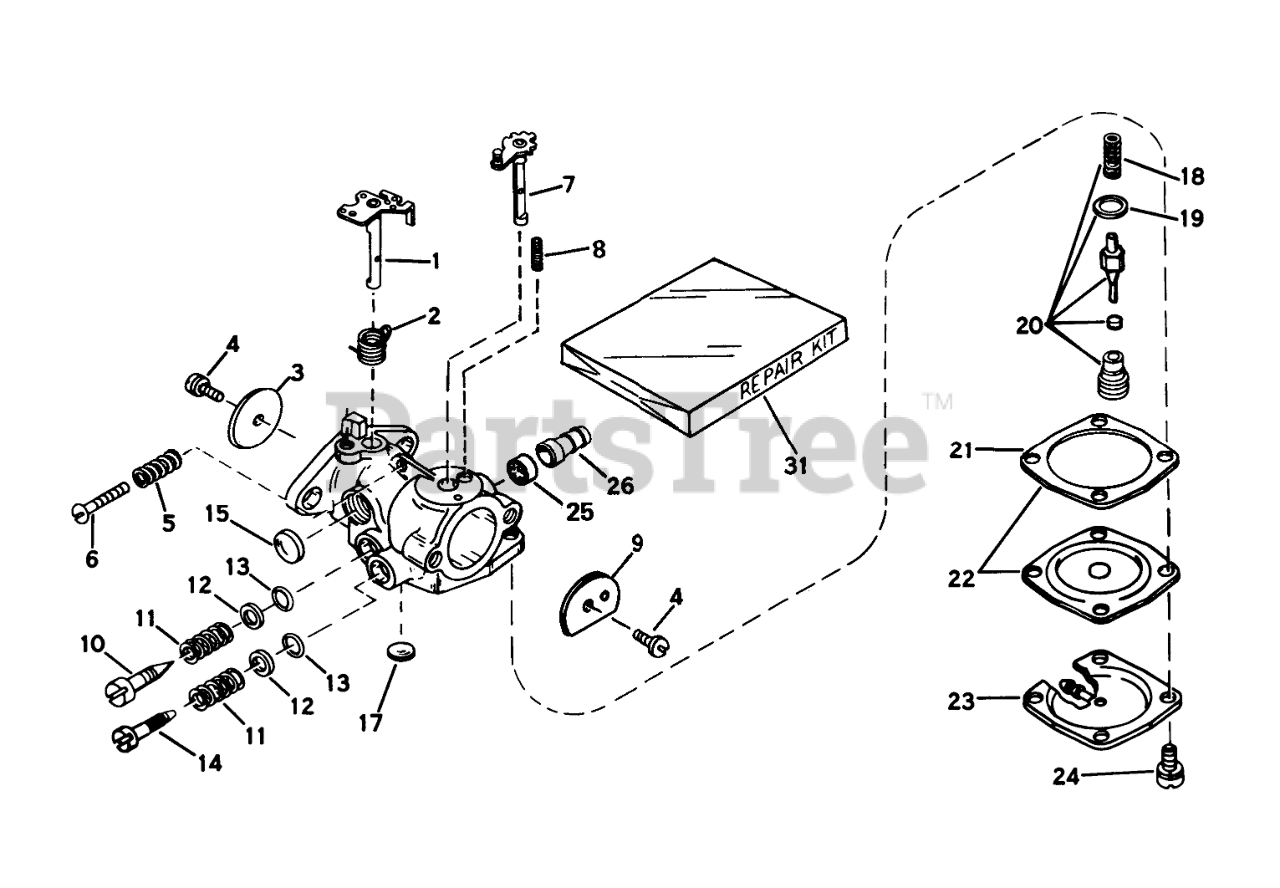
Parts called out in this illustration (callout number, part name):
1	Shaft & Lever Assy., Throttle
2	Spring Return
3	Shutter, Throttle
4	Screw-Shutter
5	Spring-Tension
6	Screw-Throttle Crack Screw / Idle Speed
7	Shaft & Lever Assy., Choke
8	Spring-Positioning, Choke
9	Shutter-Choke
10	Screw-Idle Adjustment
13	"O"Ring
14	Screw Main Adjustment
15	Plug-Welch, Idle Mixture Well
17	Plug Welch
18	Spring-Valve
19	Gasket-Valve Seat
20	Inlet Needle, Seat, Spring & Gasket Assy. (lncl. #18&19)
21	Gasket-Diaphragm
22	Diaphragm Assy. (Incl. #21)
23	Cover, Diaphragm
24	Screw, Diaphragm Cover
25	Valve Check
26	Fuel Fitting
31	Kit-Repair
